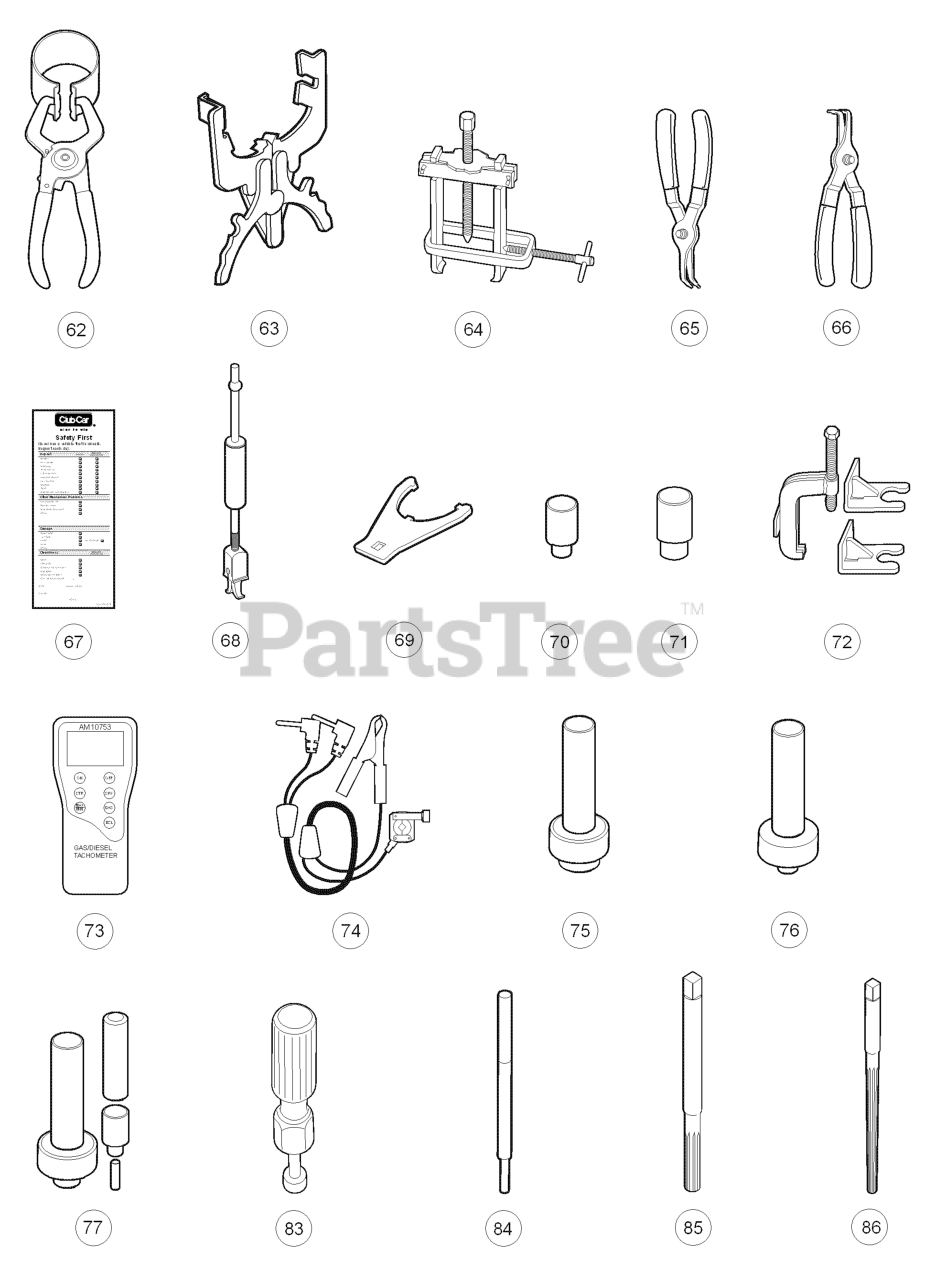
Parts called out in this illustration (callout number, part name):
62	KIT, PISTON RING COMPRESSOR
63	PISTON RING PLIER
64	SPECIAL-USE PULLER SET
65	EXTERNAL SNAP RING PLIERS
66	INTERNAL SNAP RING PLIER 9O
67	SAFETY FIRST CARD
68	SEAL PULLER
69	WRENCH, SPANNER
70	Steering Column Bearing Press Tool
71	TOOL-STEERING RETAINING RING
72	PULLER, STEERING WHEEL
73	TACHOMETER GAS/DIESEL
74	TACHOMETER DIESEL ADAPTOR
75	TRANS-AXLE, AXLE SEAL TOOL
76	Transaxle Pinion Seal Tool
77	Transmission Tool Kit
82	VALVE CLEAR ADJ SCREW HOLDER
83	DRIVER, VALVE GUIDE, 6.6. MM
84	VALVE GUIDE REAMER
85	REAMER-VALVE GUIDE
